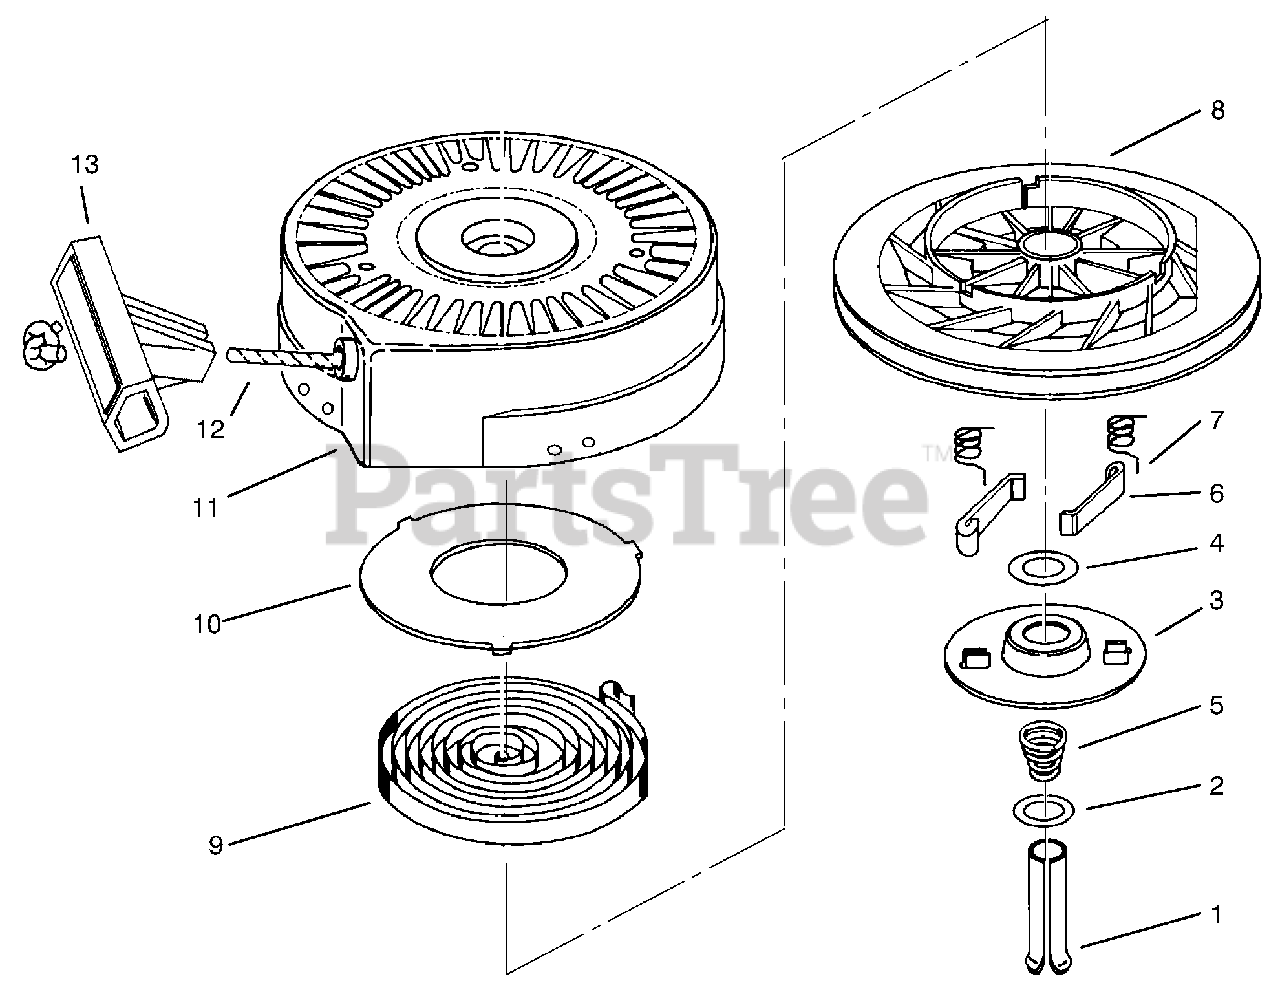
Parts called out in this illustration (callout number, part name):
1	Spring Pin (Incl. Ref. #4)
3	Retainer
5	Brake Spring
6	Starter Dog
7	Dog Spring
8	Pulley Assembly (Incl. Ref. #9 & 10)
9	Rewind Spring
10	Spring Cover
11	Starter Housing Assembly
12	Starter Rope
13	Starter Handle
